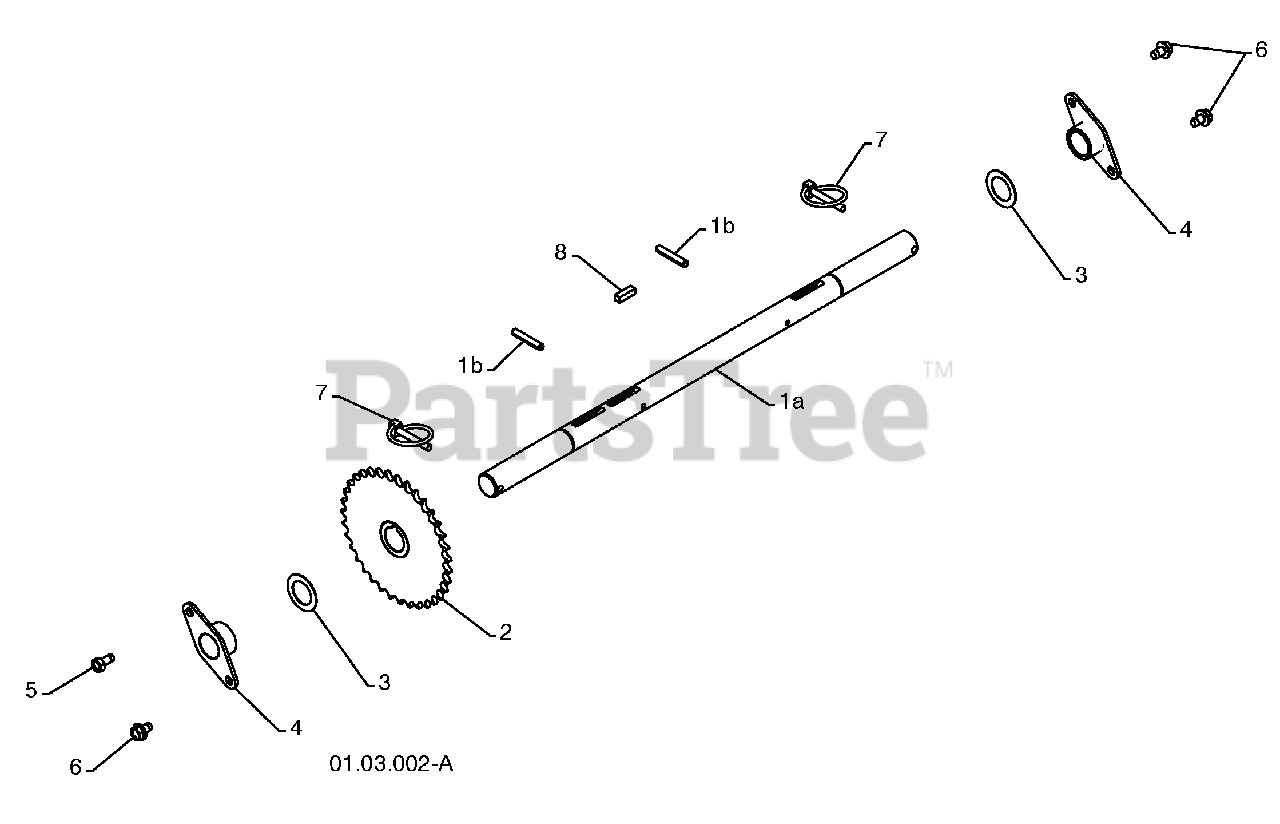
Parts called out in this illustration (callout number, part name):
1	AXLE ASSEMBLY (assy of 1a,1b)
2	SPROCKET
3	THRUST WASHER
4	BEARING
5	SCREW 5/16-18 X .625
6	SCREW 5/16-18 X .500
7	KLIK PIN 1/4 X 1.50
8	SQUARE KEY
